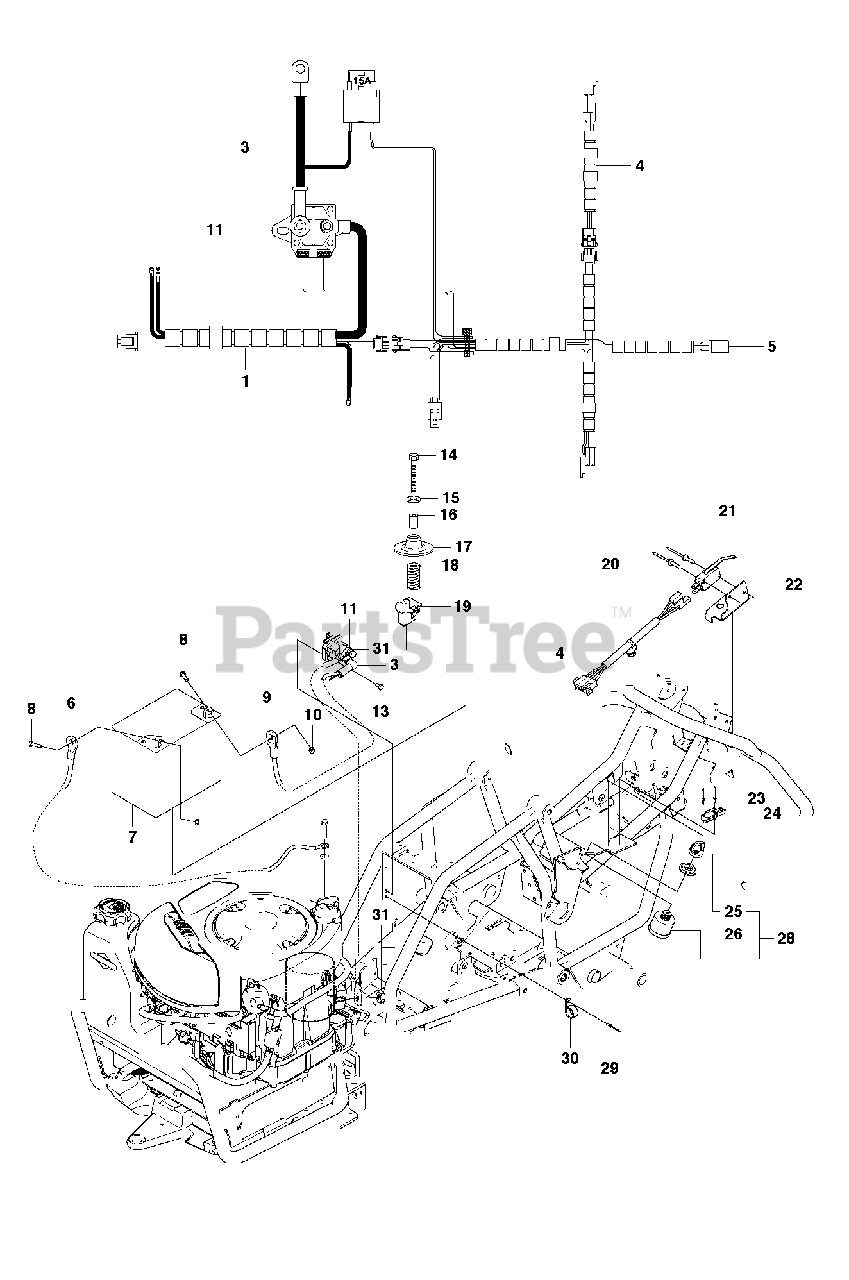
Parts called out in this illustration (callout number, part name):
8	SCREW EHHM
14	SCREW
16	SPACER TUBE
21	MICRO SWITCH
24	MICRO SWITCH
25	IGNITION KEY
26	NUT
28	IGNITION SWITCH
